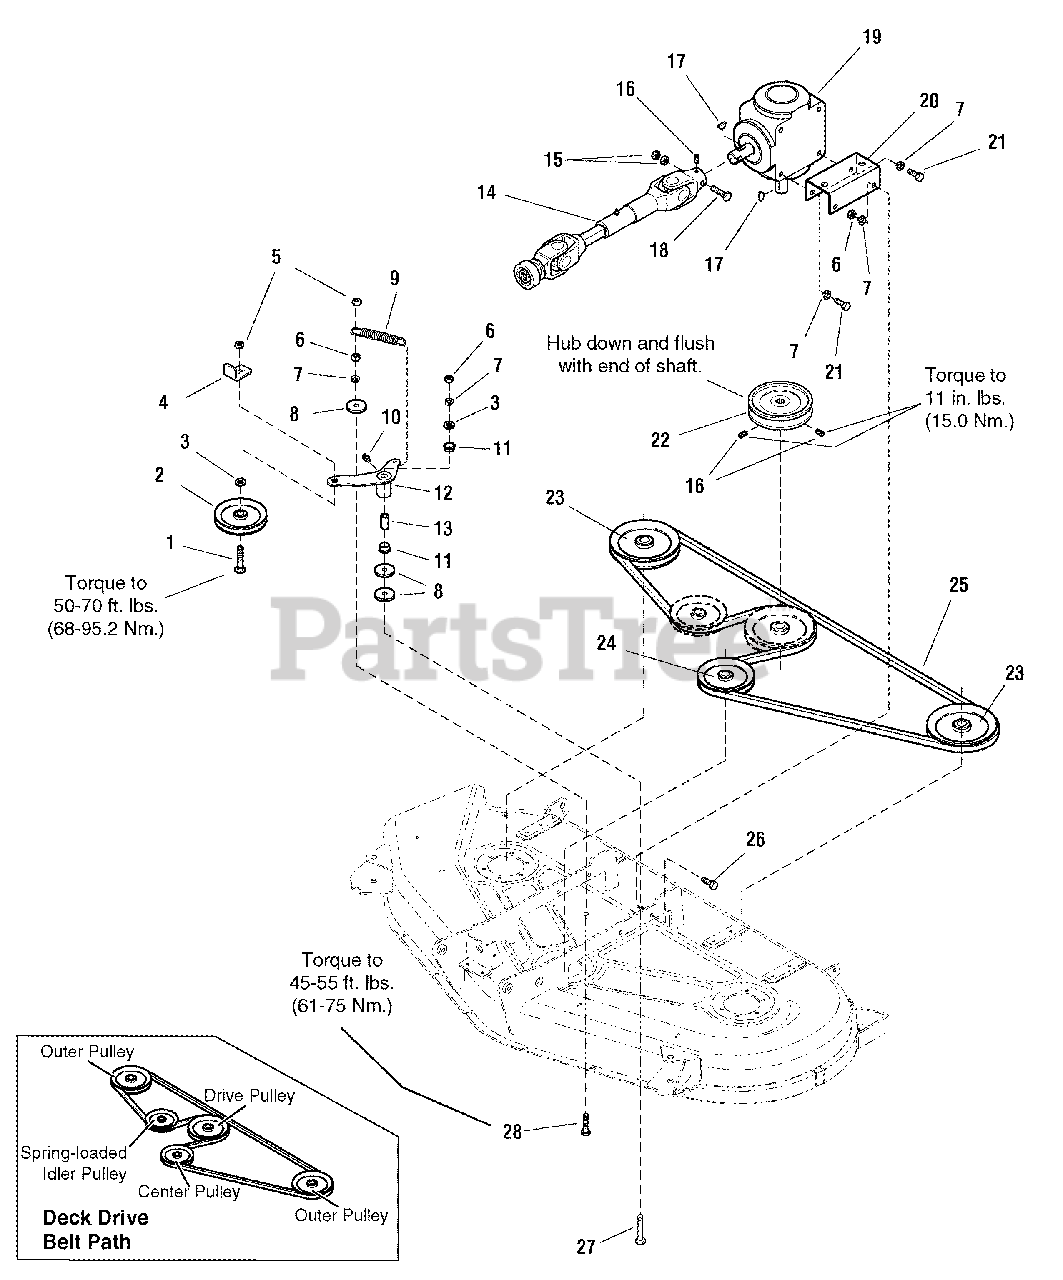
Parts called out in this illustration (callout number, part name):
1	CAPSCREW, Hex Head, 3/8-16 x 1-1/4
2	PULLEY, Idler, Spring-loaded
3	WASHER, Plain, 3/8
4	STOP, Idler
5	NUT, Hex, Center Lock, 3/8-16
6	NUT, 3/8-16
7	LOCKWASHER, 3/8
8	WASHER
9	SPRING, Extension
10	FITTING, Lube
12	ASSEMBLY, Lever & Hub, Idler
14	DRIVE SHAFT, Complete (See Drive Shaft Service Parts )
15	NUT, Hex, Center Lock, 1/4-20
16	SET SCREW, Square Head, 5/16-18 x 1/2, G8
17	KEY, HI PRO 1/4 x 7/8
18	CAPSCREW, Hex Head, 1/4-20 x 2-1/4
19	GEAR BOX, 54" Mower Deck (See Gear Box Service Parts )
20	BRACKET, U, 5-1/2 x 2
21	CAPSCREW, Hex Head, 3/8-16 x 3/4,
22	PULLEY, Gear Box
23	PULLEY, Side Arbor
24	PULLEY, Center Arbor
26	CAPSCREW, Hex Head, 3/8-16 x 1
27	CAPSCREW, Hex Head, 3/8-16 x 2-3/4,
28	CAPSCREW, Hex Head, 3/8-16 x 1-1/2
